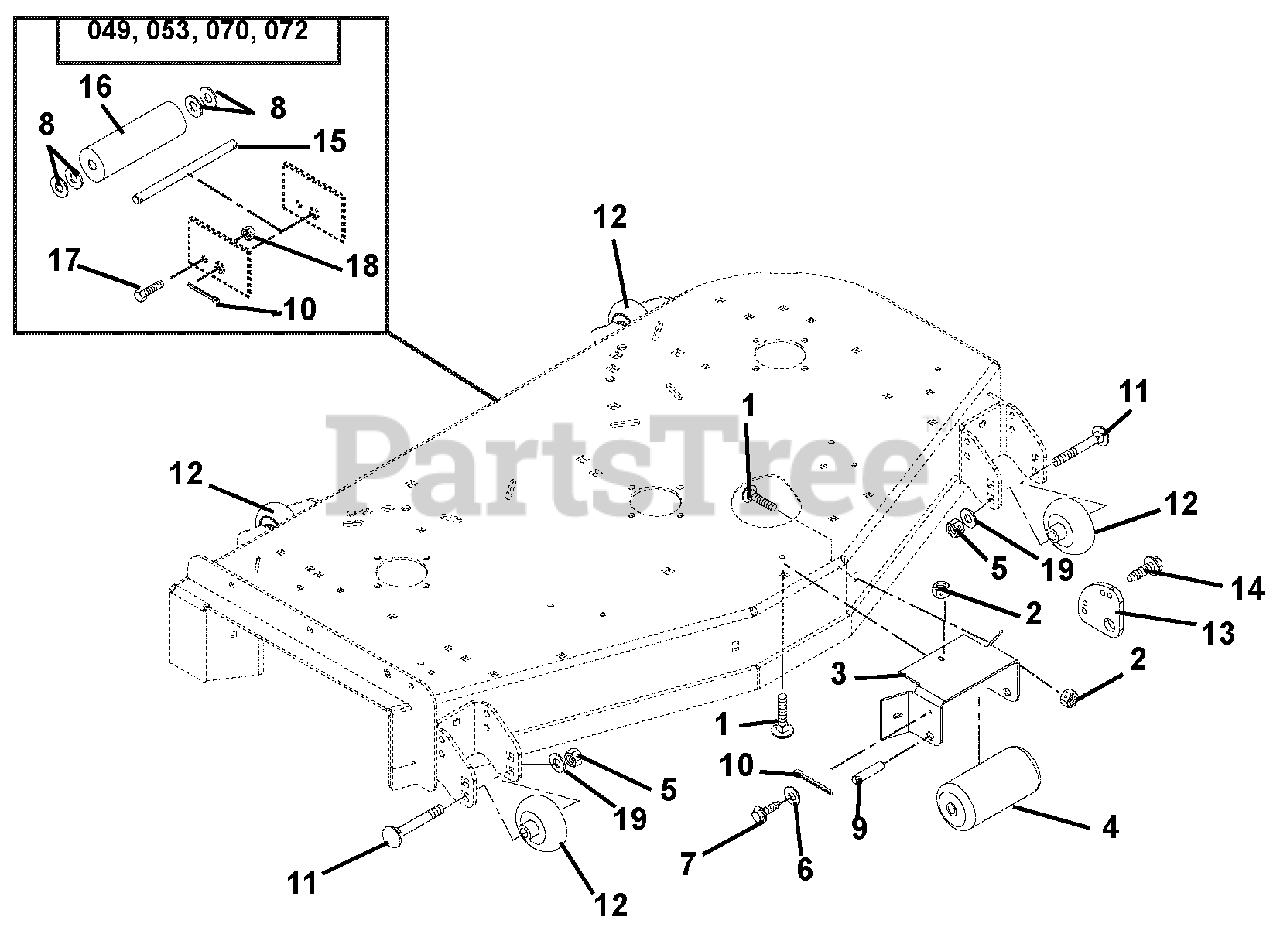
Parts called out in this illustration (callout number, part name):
1	Bolt-Round Head Square Neck .38-16 x 1.00 Grade 5
2	Nut-Locking-Top-Flange .38-16
3	Bracket- Anti-Scalp Roller
5	Nut-Locking-Nylon .50-13
6	Washer-Flat-Steel .281 x .62 x .065
7	Screw-Tapping .25-20 x .75 Hex Washer Head
8	Washer-Flat-Steel .656 x 1.31 x .095 (086, 091, 107)
10	Pin-Cotter .25 x 2.00 (045, 046, 047, 052, 066, 067, 068, 071, 084, 085, 087, 088, 089, 102, 103, 104,
11	Bolt-Round Head Square Neck .50-13 x 5.00 Grade 2
12	Wheel, 3 x 5
13	Anti-Scalp Washer
14	Screw-Tapping .25-20 x .62 Hex Washer Head
15	Shift, Center Roller (086, 091, 107)
16	Roller, Gage (086, 091, 107)
17	Bolt-Hex .25-20 x .75 Grade 5 (086, 091, 107)
18	Nut-Locking-Center .25-20 (086, 091, 107)
19	Washer-Flat-Steel .531 x 1.06 x .095
